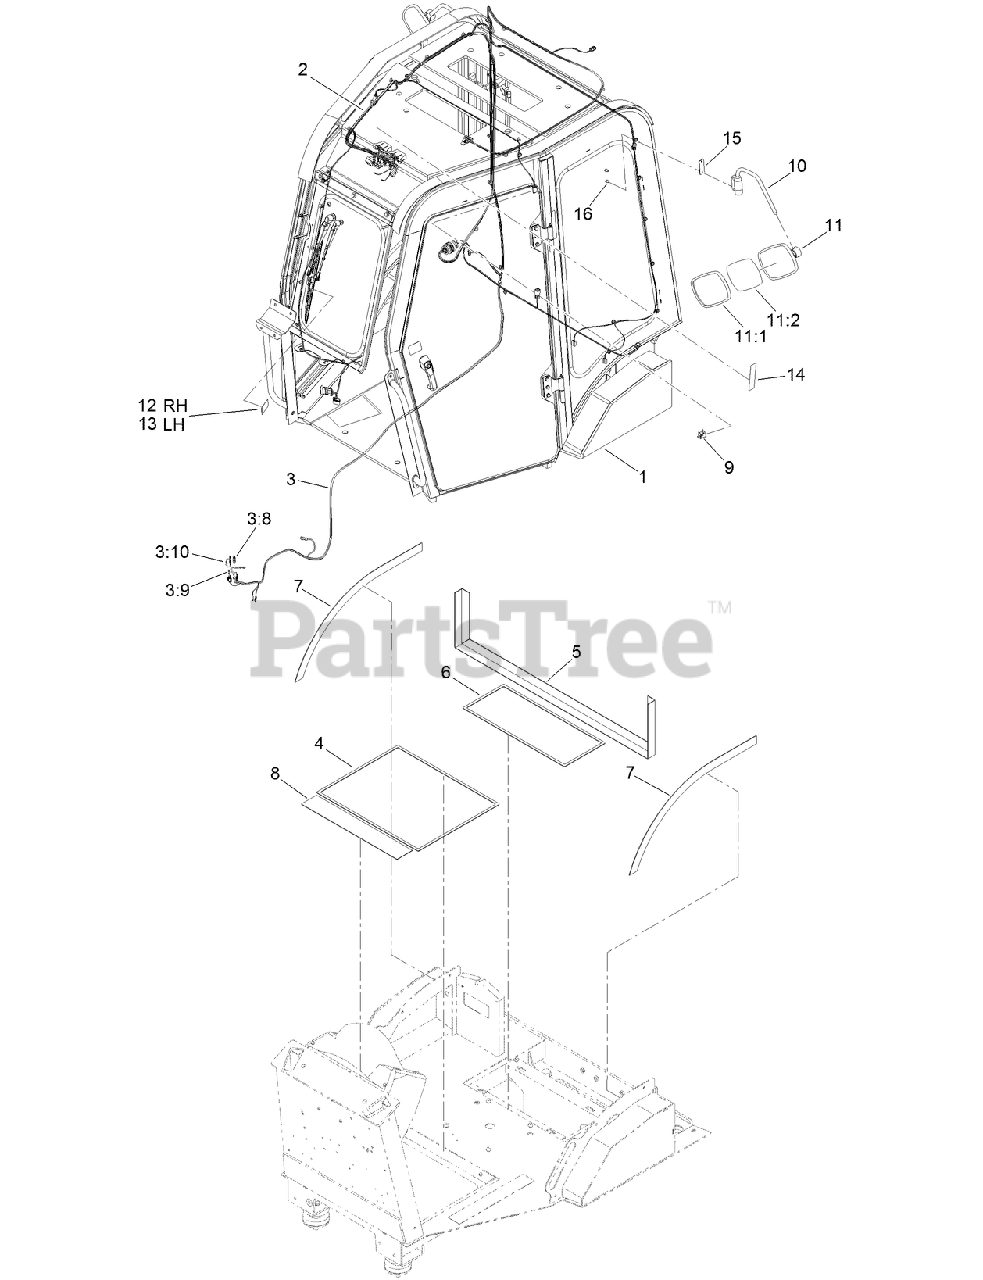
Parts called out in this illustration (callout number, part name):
1	CAB ASM
2	HARNESS-WIRE, INSIDE
3	HARNESS-WIRE, OUTSIDE
3:8	FUSE-MAXI, 60 AMP
3:9	FUSE-BLADE, 10 AMP
3:10	COVER-FUSE, SINGLE
4	GASKET-COVER, TRACTION PEDAL
5	SEAL-REAR, PRESSURE
6	GASKET-COVER, BATTERY
7	SEAL-FENDER
8	SEAL-FLOOR, FIREWALL
9	SWITCH-BAIL
10	ARM-MIRROR, SIDE
11	SIDE MIRROR ASM
11:1	MIRROR
11:2	GASKET
12	DECAL-DOOR LATCH, RIGHT
13	DECAL-DOOR LATCH, LEFT
14	DECAL-WARNING
15	GASKET-MIRROR
16	SCREW-HHF
